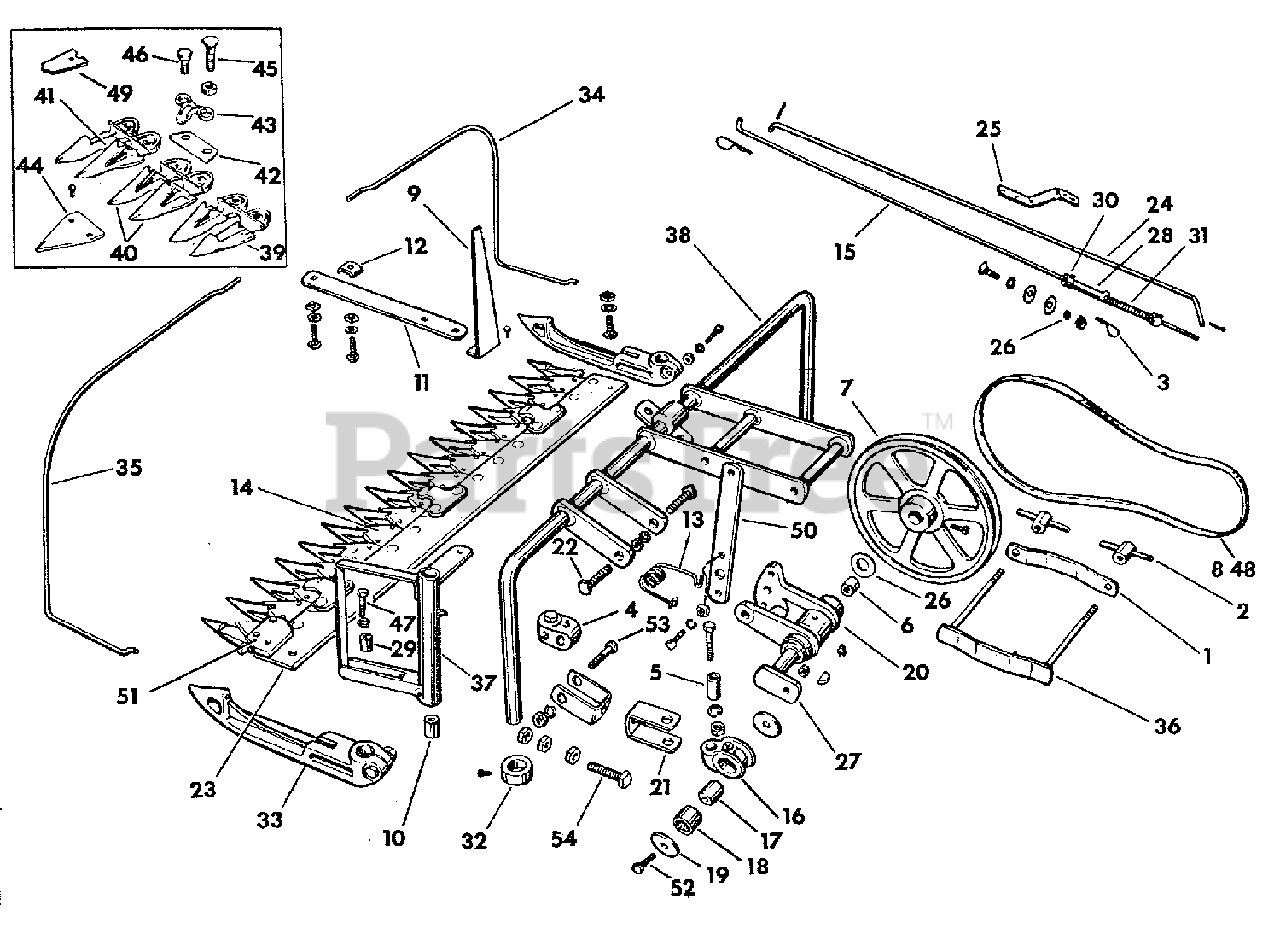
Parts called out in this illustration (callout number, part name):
1	SIDE PLATE, Hitch
2	T-NUT, Complete
3	CLIP, Spring
4	PIVOT BLOCK
5	BEARING, Pivot Block
6	BUSHING, Bearing Bracket
8	BELT, 33" (1-1/2 HP)
10	BUSHING, Sickle Crank
11	BRACKET, Grass Finger
12	CLAMP, Grass Finger
13	SPRING, Belt Release
14	SICKLE, Complete w/Head
15	ROD, Lower Idler
16	HOUSING, Pitman Bearing
17	INNER RACE, Pitman Bearing
18	NEEDLE BEARING, Pitman
19	WASHER, Pitman Bearing
20	BRACKET, Bearing
21	CLEVIS, Pitman
22	CAPSCREW, Special
23	CUTTER BAR, 30"
24	ROD, Upper Idler
25	IDLER LEVER, Lower
26	BUSHING, Idler Lever
27	SHAFT ASSEMBLY, Crank
28	SOCKET ASSEMBLY, Rod
29	BUSHING, Sickle Head
30	COLLAR, Set
32	COLLAR, Set
33	SHOE, Sickle Bar
34	GRASS FINGER, Right
35	GRASS FINGER, Left
36	CLAMP, Hitch
37	BELL CRANK, Sickle
38	FRAME, Sickle Bar
39	GUARD, Left End
40	GUARD, Twin
41	GUARD, Right End
42	PLATE, Wear
43	CLIP, Sickle
44	SICKLE SECTIONS (15 Sections and 30 Rivets in box)
45	GUARD BOLT, Long
46	GUARD BOLT, Short
48	BELT, "V", 3HP
49	PLATES, Ledger
50	ARM ASSEMBLY, Clutch
51	SICKLE HEAD
